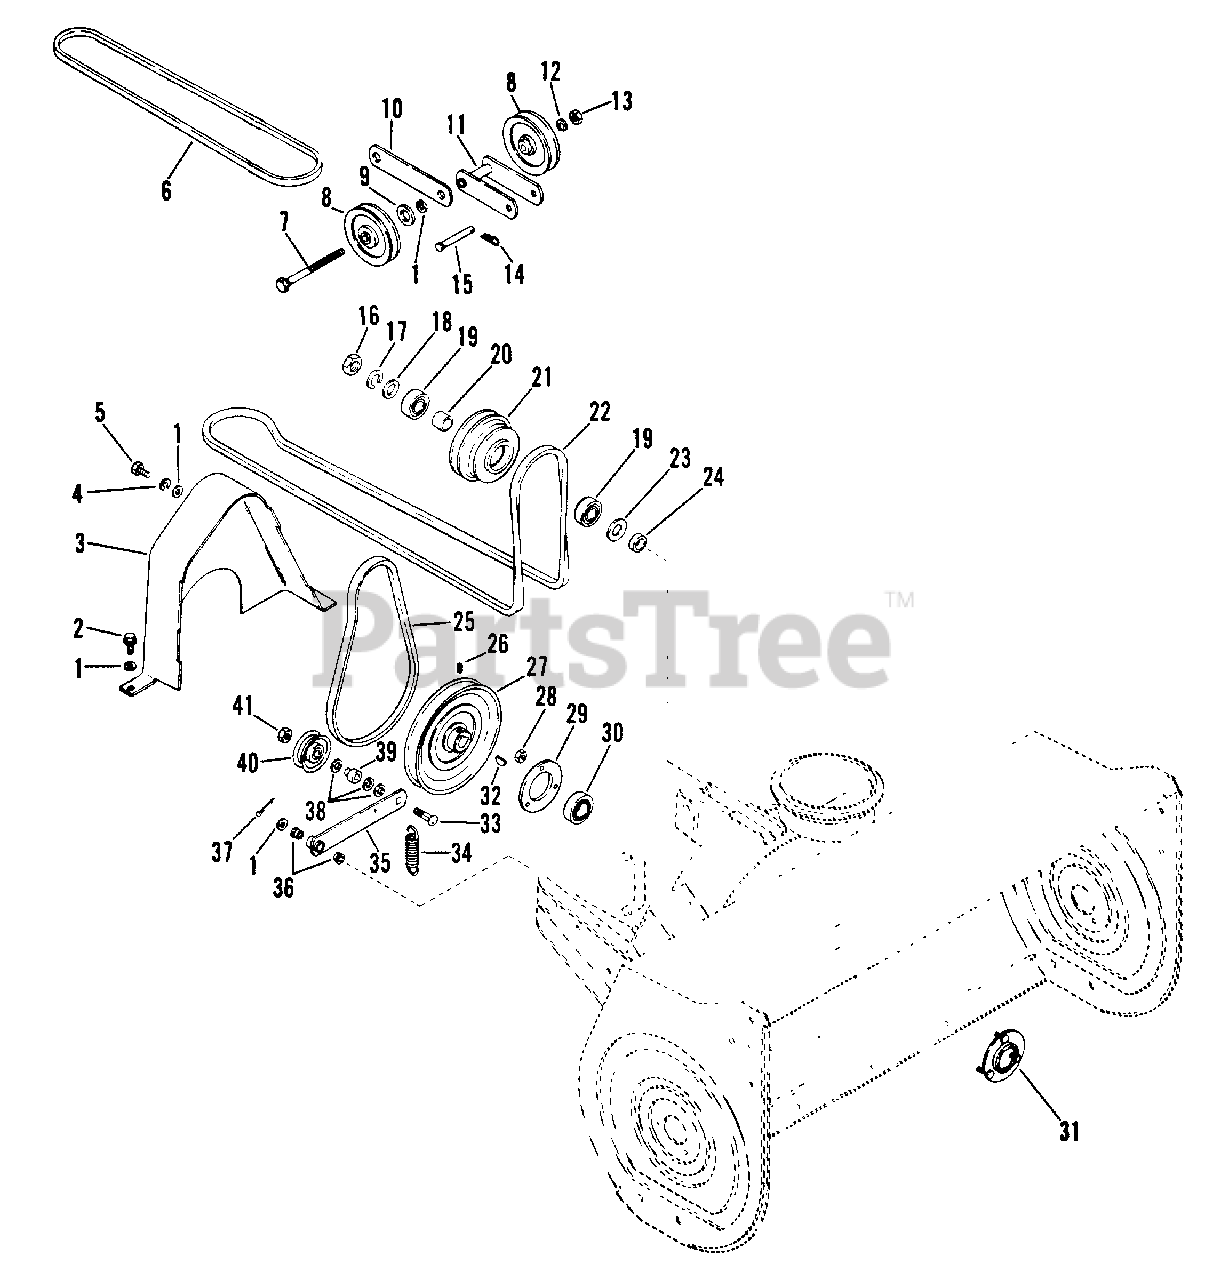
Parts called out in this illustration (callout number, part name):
1	Washer, Flat .406x.812x.065
2	Taptite, 5/16-18x.50
3	Guard, Belt
4	Washer, Lock 5/16 SP
5	Bolt, Hex 5/16-18x.75
6	Belt
7	Bolt, Hex 3/8-16x5.00
8	Idler, .375x4
9	Washer, Flat .813x1.37x.100
10	Strap
11	Bracket, Idler
12	Washer, Lock 3/8 Reg.
13	Nut, Hex 3/8-16
14	Hairpin, Internal
15	Pin, Clevis
16	Nut, Jam 3/4-10 Hex
17	Lockwasher, Internal .75 I.D.
18	Washer, .770x1.250x06
19	Bearing, Radial
20	Spacer
21	Sheave
22	V-Belt, .5x109" 4L
23	Washer, .774/.811x1.500x.187
24	Spacer
25	V-Belt
26	Set Screw, 5/16-18x.50 SKH
27	Sheave, .625x7.50
28	Nut, Lock 1/4-20
29	Bearing, Flange
30	Bearing, Ball
31	Bearing, Flange
32	Key, Wdrff .187x.875 HRD #11
33	Bolt, 3/8-16x1.50 Rd Hd Sq Nk
34	Spring, Ext. 3-1/2 Free Length
35	Arm, Idler
36	Bushing, Flange .375x.500x.312
37	Pin, Cotter .125x.75
38	Washer, Flat .531x1.062x.095
39	Spacer
41	Nut, Lock 3/8-16
